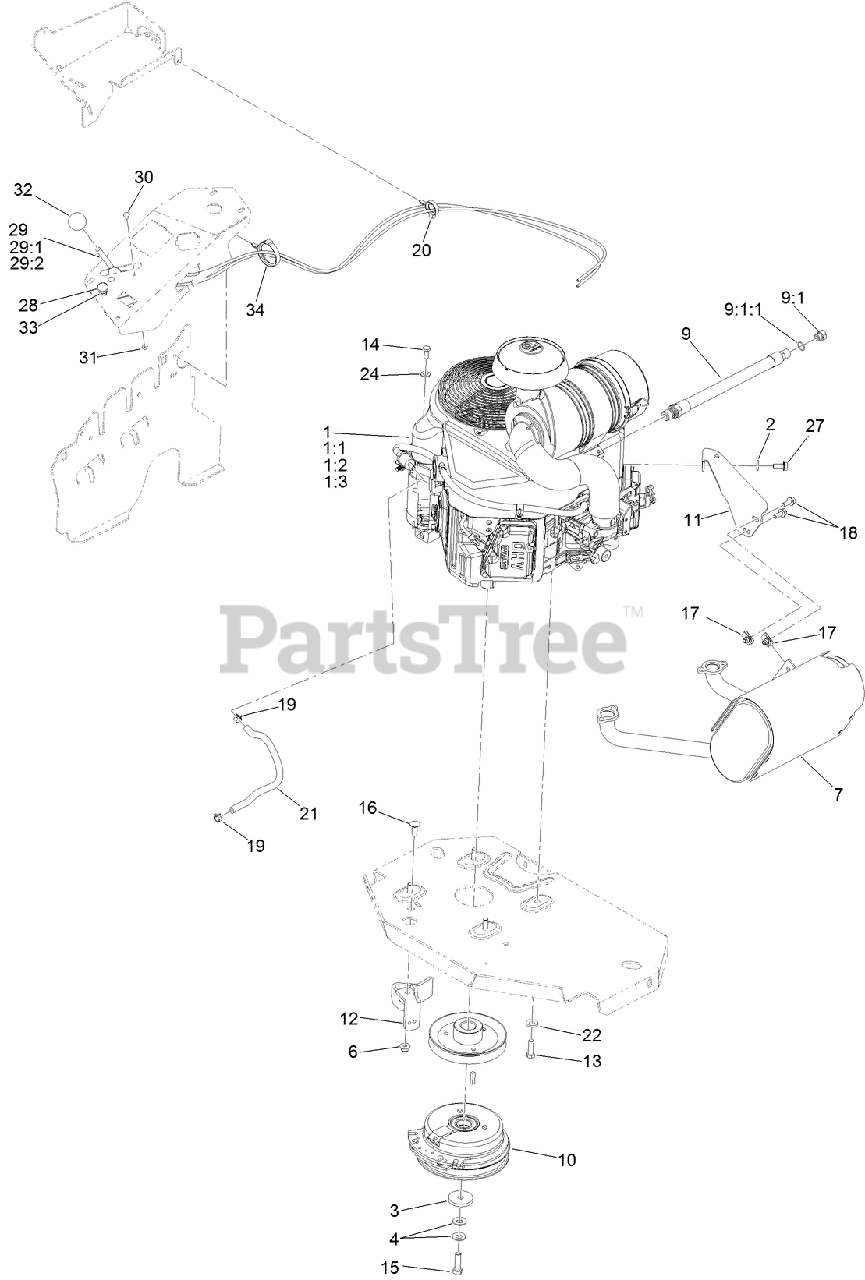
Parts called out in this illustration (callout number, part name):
1:1	KAWASAKI 49065-7007 ENGINE OIL FILTER
1:2	KAWASAKI 11013-7044 ENGINE AIR FILTER
1:3	KAWASAKI 11013-7045 SAFETY FILTER
2	WASHER-SPRING
3	WASHER-CLUTCH
4	WASHER-SPRING
6	NUT-HF, NI
7	MUFFLER
9	ENGINE OIL DRAIN HOSE ASM
9:1	PLUG-HH
9:1:1	O-RING
10	CLUTCH
11	BRACKET-MUFFLER
12	CLUTCH-ANCHOR
13	SCREW-HH
14	SCREW-HH
15	SCREW-HH, W/LOCTITE
16	SCREW-CARR
17	NUT-U
18	SCREW-HHF
19	CLAMP-HOSE
20	CLAMP-HOSE
21	HOSE-FUEL
22	WASHER-BELLEVILLE
24	WASHER-PLAIN
27	SCREW-HHF
28	CONTROL-CHOKE
29	THROTTLE CONTROL ASM
29:1	LEVER-THROTTLE
30	BOLT-CARR
31	NUT-LOCK, NI
32	KNOB-BALL
33	NUT-HJ
34	CLAMP-HARNESS
